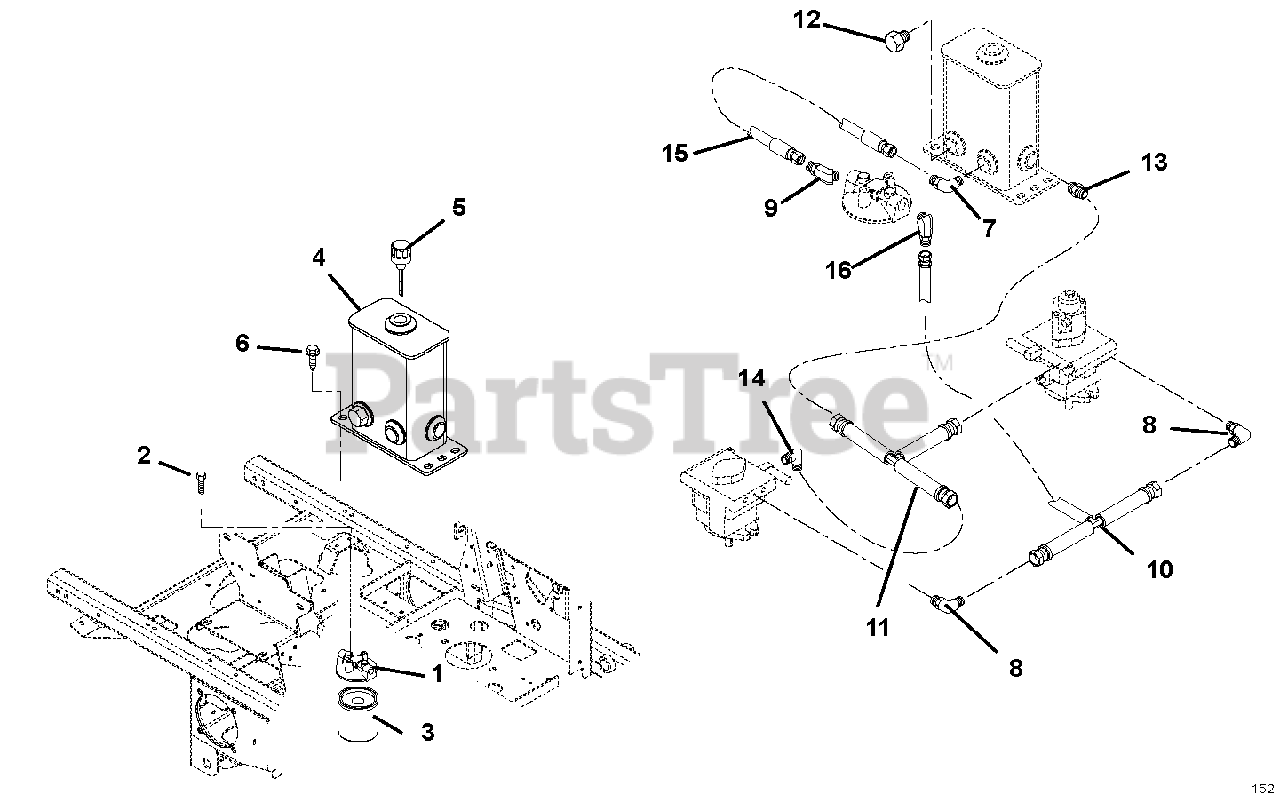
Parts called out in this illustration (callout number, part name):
1	Head, Filter (Serial Numbers 000101 and 000400)
2	Bolt, Hex .25-20 x .50 Grade 5 Epoxy
3	Oil Filter
4	Weldment, Hydraulic Tank (SN 000101 - 002499)
5	Hydraulic Tank Dipstick
6	Screw, Tapping .38-16 x .75 Hex Washer Head
7	Fitting, Hydraulic 90 Degree Elbow
8	Fitting, Elbow M6O-M8F
9	Fitting, Hydraulic 45° M80-M120 (SN 000101 - 000400)
10	Hose, Tee Assembly, .50
11	Hose, .38 Tee Assembly
12	Plug, Hex, .75-16 O-Ring
13	Fitting, Hydraulic 45 Degree M6F-M8O (SN 000101- 002499)
14	Fitting, Hydraulic (6 C5OLO)
15	Hose, Hydraulic (SN 000101 - 000400)
16	Fitting, Hydraulic 45° M80-M120 (SN 000101 - 000400)
